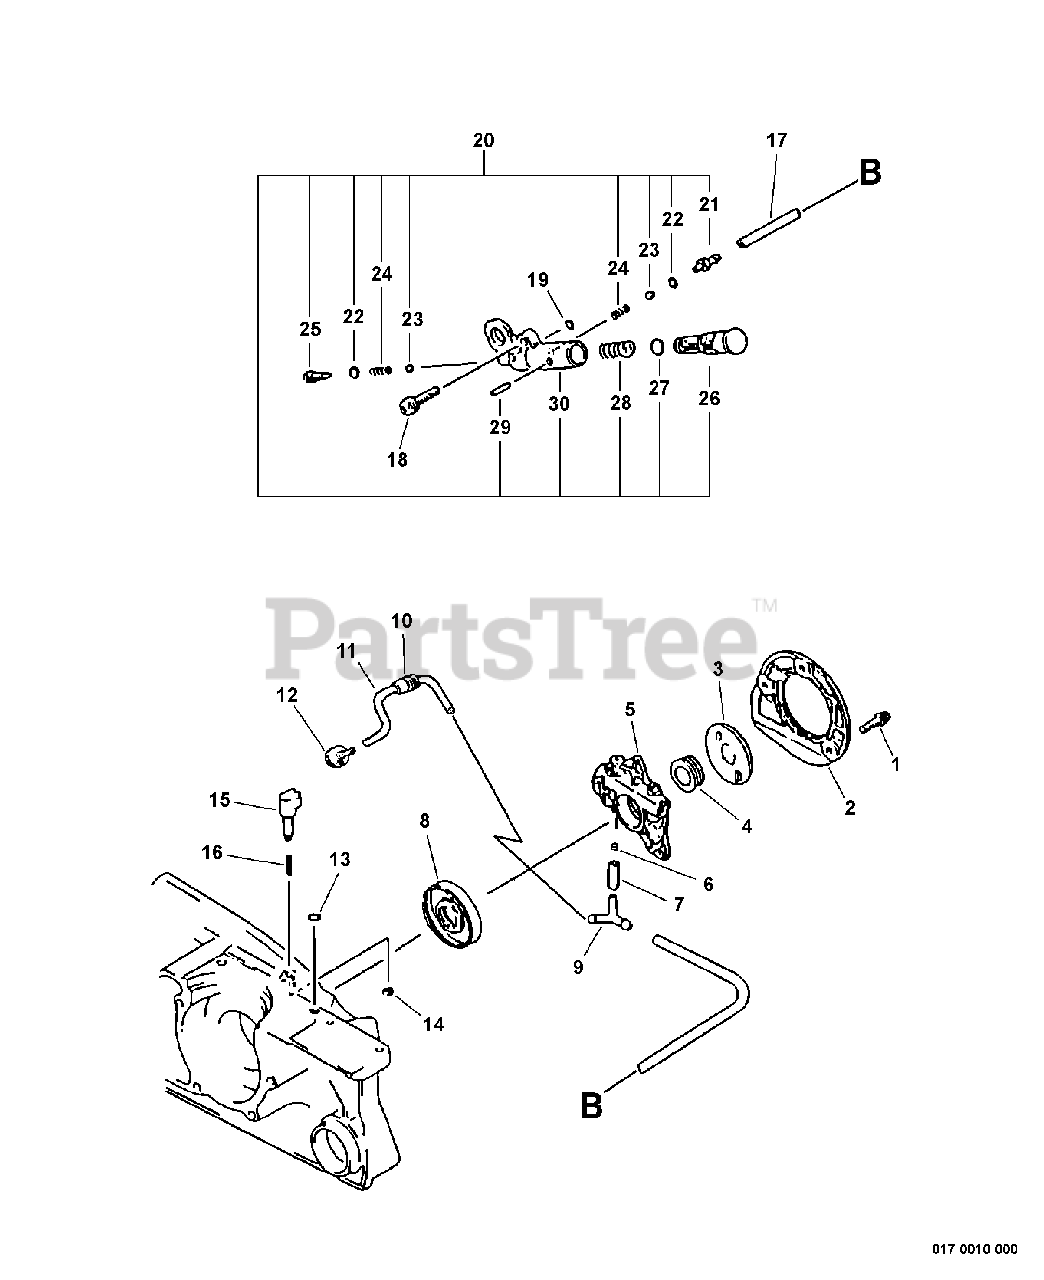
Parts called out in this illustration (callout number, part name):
1	SCREW - 4X14
2	COVER, OIL PUMP
4	GEAR - WORM
5	AUTO-OILER ASSY
6	CLIP - 6.5
7	PIPE - 3X6X20 -- BLACK
8	SEAL, OIL
9	CONNECTOR, PIPE
11	PIPE - OIL
12	FILTER, OIL
13	O-RING - 3
14	RING, RETAINING - 3
15	DIAL, AUTO-OILER
17	PIPE - 3X6X210 -- BLACK
18	SCREW - 5X20
19	O-RING - 3
20	OIL PUMP ASSY
20	OILER ASSY - ORANGE
23	VALVE, BALL
25	ADAPTER, OIL PUMP
26	PISTON, OIL PUMP
27	O-RING - 7
29	PIN - SPRING -- 2X16
30	BODY, OIL PUMP
